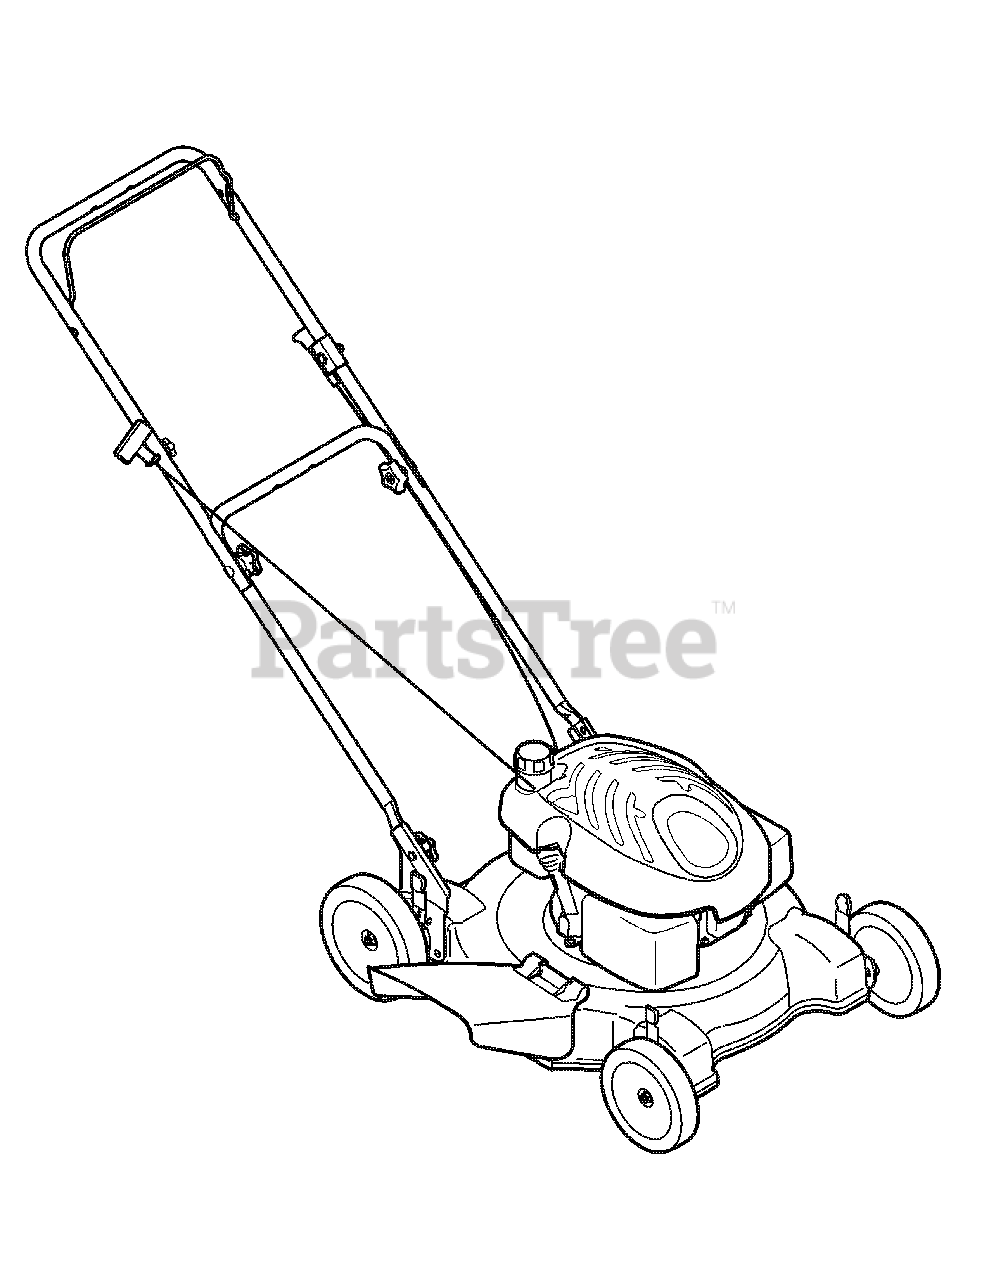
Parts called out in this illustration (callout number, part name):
NA	Pre-Filter
NA	Drive Belt
NA	Drive Cable
NA	Grass Bag
